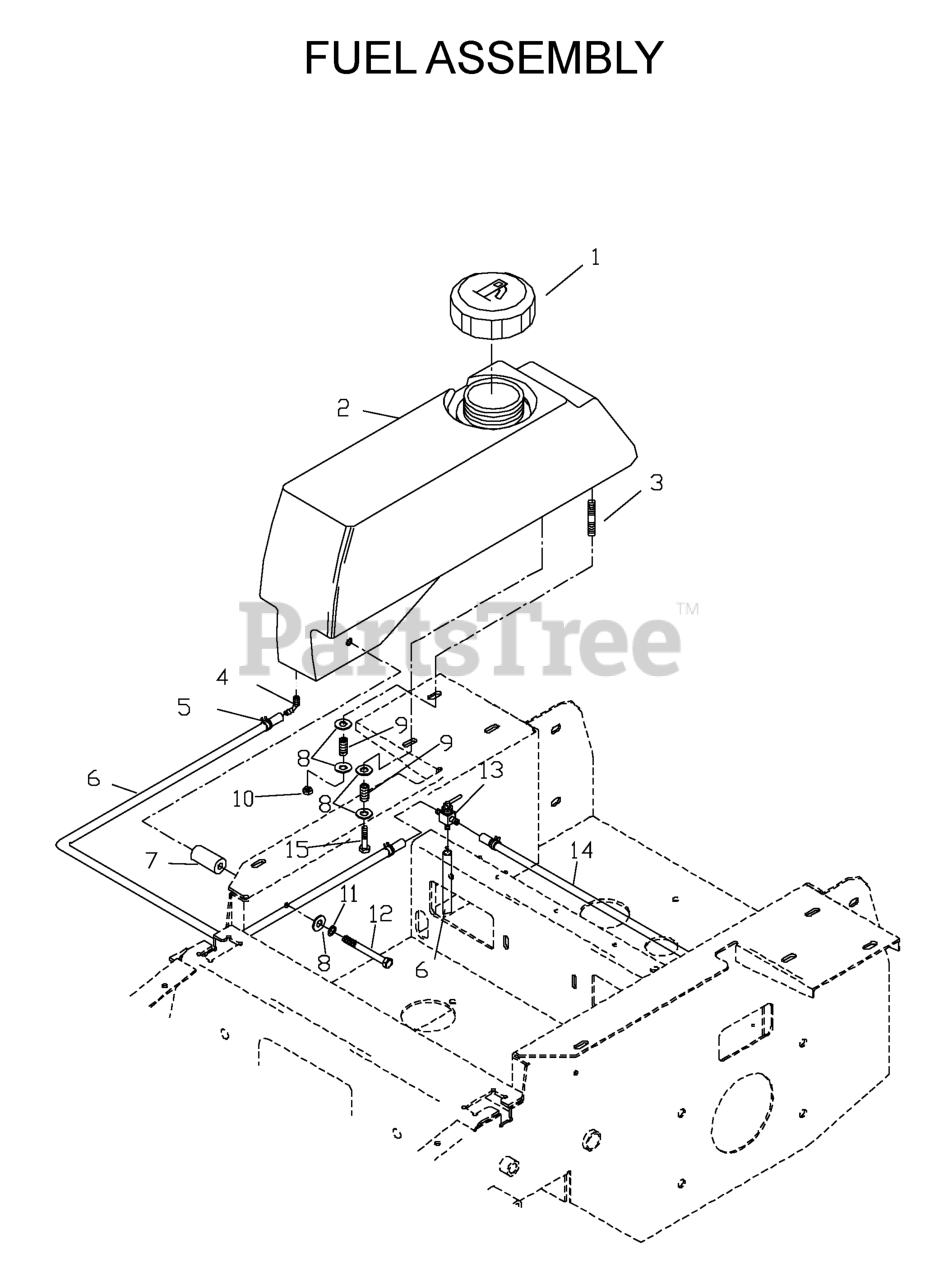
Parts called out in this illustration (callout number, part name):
1	FUEL CAP
2	FUEL TANK RT
3	STUD, 5/16C
4	HOSE BARB 90 DEGREE
5	HOSE CLAMP
7	TANK SPACER
8	WASHER 5/16 FLAT
10	NUT 5/16C CENTERLOCK
11	WASHER.LOCK.HVY.HLCL.SPR.5/16
12	HCS 5/16C X 4
13	FUEL VALVE
15	HCS 5/16C X 1
539104409	LEFT TANK W/CUP HOLDER
